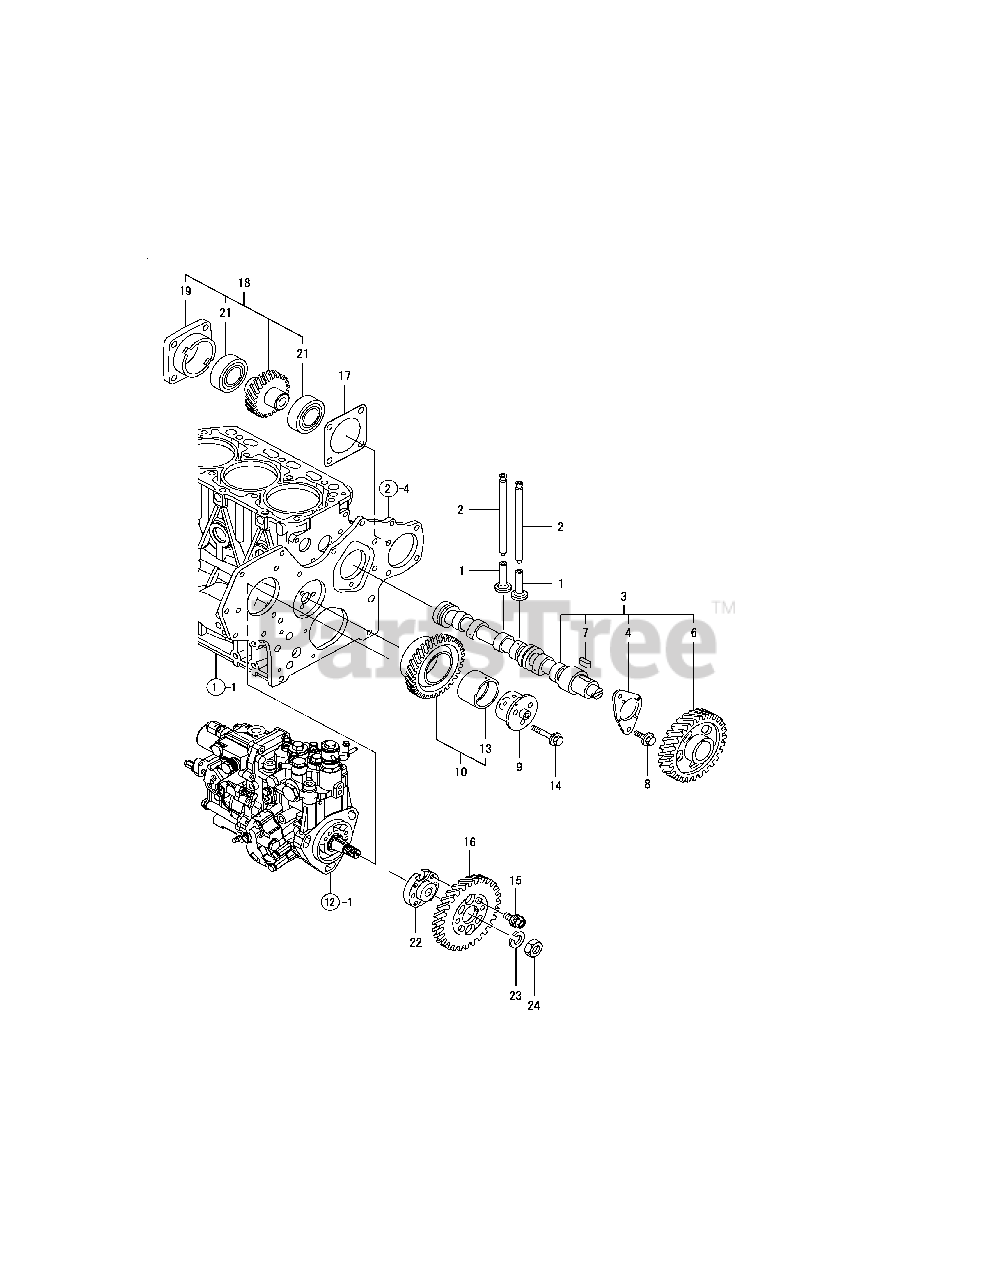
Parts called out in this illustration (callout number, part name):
4	METAL, THRUST CAM
6	GEAR, CAMSHAFT
8	BOLT 8X 14 PLATED
9	SHAFT, IDLE GEAR
10	GEAR ASSY, IDLE
13	BUSH, IDLE GEAR
14	BOLT M 8X 40 PLATED
15	BOLT, INJECTION PUMP GEAR
17	GASKET, (NON ASB.)
18	GEAR ASSY, HYD PUMP CAM
19	BRACKET, HYD PUMP GEAR
23	SPRING WASHER 14
24	LOCK NUT M14 PLATED
